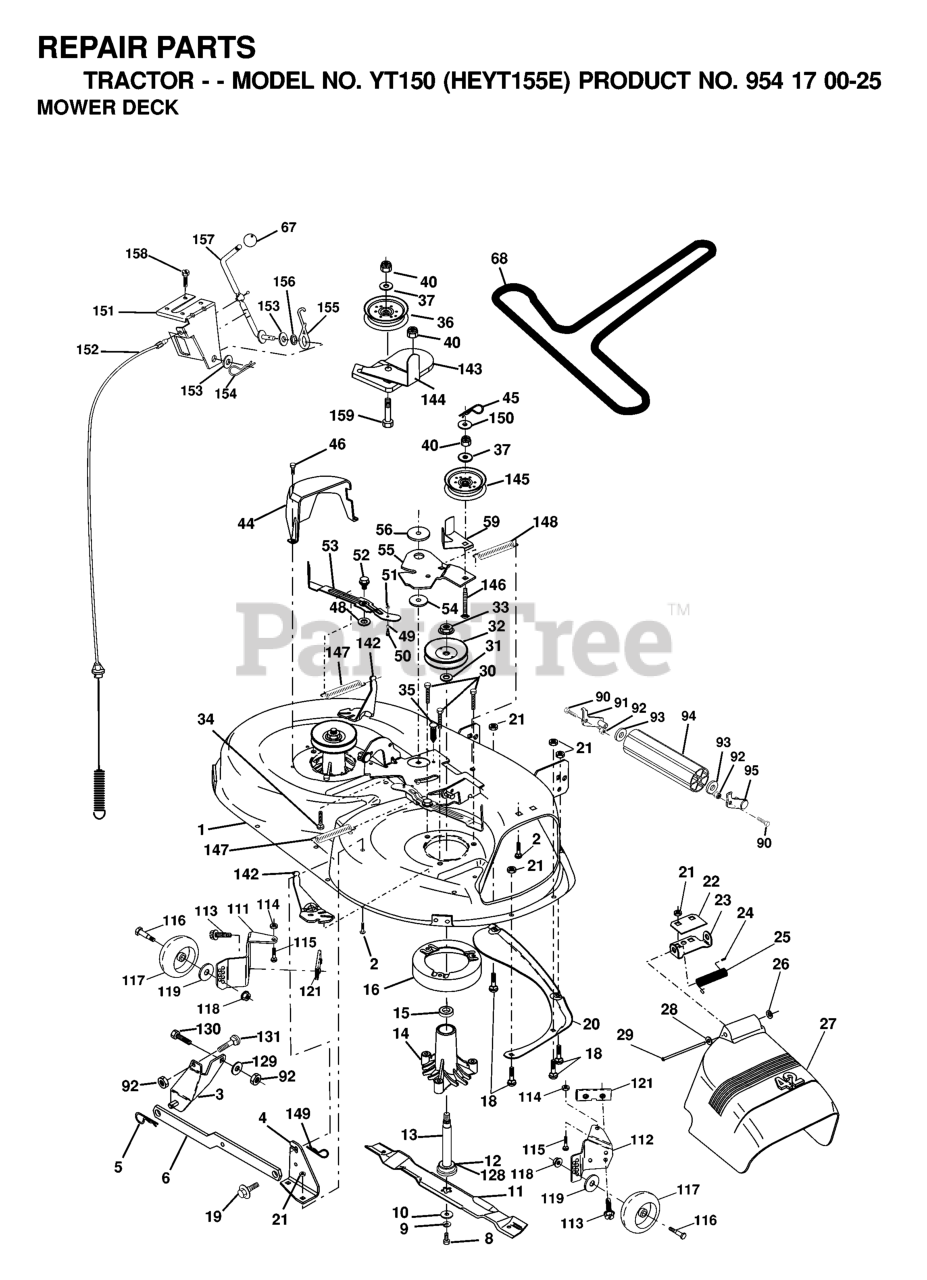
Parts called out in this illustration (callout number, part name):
1	42" DECK KIT
2	RP BOLT 5/16-18 X3/4 ZN/YEL GR
3	BRKT ASM SWAY BAR
4	BRACKET SWAY BAR 42" DECK
5	RETAINER-SPRNG RB
6	REAR SUSP ARM
8	BLADE BOLT
9	LOCKWASHER
10	WASHER.BLADE
11	BLADE 42", YTH 160
12	BEARING.BALL.#6204.(MANDREL)
13	SHAFT ASM VENT
14	HOUSING.MANDREL.VENTED (MACHD)
16	STRIPPER
18	BOLT
19	BOLT SHD 5/16-18
20	BAFFLE.VORTEX
21	LOCKNUT
22	STIFFENER BRACKET
23	DEFLECTOR BRACKET
24	CAP-SLEEVE LT
25	SPRING TORSION
26	NUT PUSH M
27	SHIELD DEFLECTOR
28	Washer 11/32 x 5/8 x 16 Ga SD
29	ROD.HINGE
30	SCREW THDROL ROLLING WASHER HD
31	WASHER
32	PULLEY/MANDREL
33	NUT
35	FASTENER.XMAS.TREE
36	FLAT IDLER PULLEY
37	WASHER
44	GUARD MANDREL LH BLACK
45	RETAINER M
46	SCREW.1/4-20X5/8
49	ROLLER ASSY
52	BOLT.SHOULDER.5/16-18
53	ARM
54	HARDENED WASHER
55	ARM IDLER 42" MOWER LT/YT
56	SPACER.RETAINER.MOWER
59	GUARD, BELT
67	KNOB T (3/8 HOLE)
90	BOLT
91	BRACKET LH (A)
92	NUT
93	Washer 1 17/32 X 7/8 X 16 Ga
94	NOSE ROLLER
95	BRACKET RH (B)
111	BRACKET WHEEL GAUGE LH 42" DK
112	BRACKET WHEEL GAUGE RH 42" DK
113	SCREW 5/16"
114	NUT
115	BOLT.CARR.5/16-18X1/2
116	BOLT M
117	WHEEL.GAUGE.STANDARD
118	LOCKNUT
119	WASHER.5/16.FLAT.STE.STD.
121	BRACKET.EXTRUDED.GAGE.WHEEL
128	WASHER FELT
129	WASHER
131	BOLT D
142	ARM SPRING BRAKE MOWER
143	BRACKET, ARM IDLER
144	DNO KEEPER.BELT.42".CLUTCH.CBL
145	PULLEY
146	BOLT, CARRIAGE IDLER
147	SPRING EXTENSION
148	IDLER RETURN SPRING
149	SPRING.RETAINER.YELLOW.ZINC
151	BRACKET.CLUTCH.CABLE
152	CLUTCH CABLE 42"
153	WASHER FLAT 3/8"
154	SPRING RETAINER
155	SPRING RETENTION LEVER
156	SPACER.CLUTCH.CABLE
157	ROD CLUTCH CABLE 3/8"
158	SCREW LT
